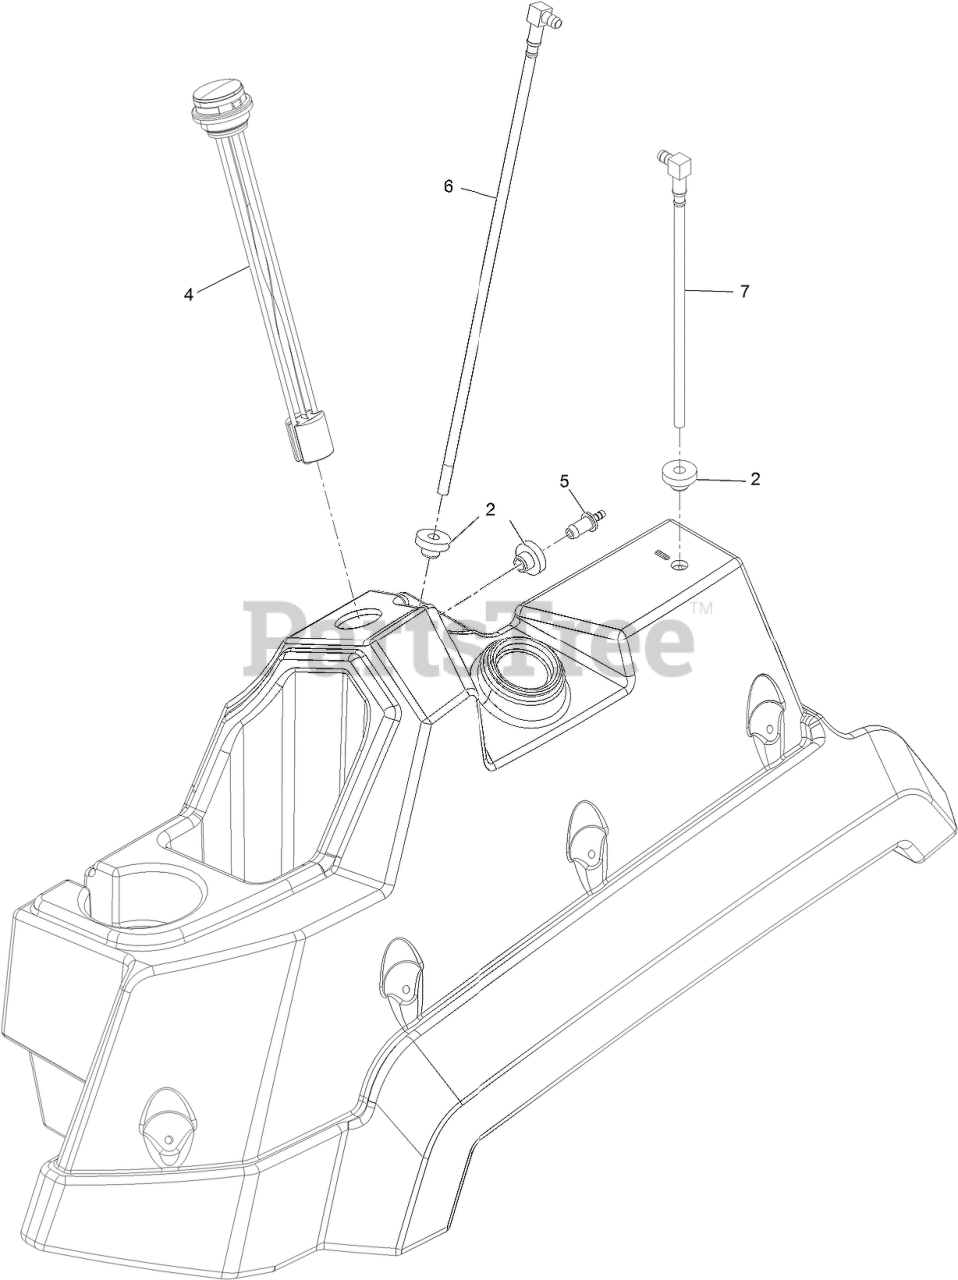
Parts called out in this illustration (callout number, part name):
2	BUSHING
4	GAUGE-FUEL
5	FITTING-ORIFICE, STRAIGHT
6	PICK-UP-FUEL
7	RETURN-FUEL
